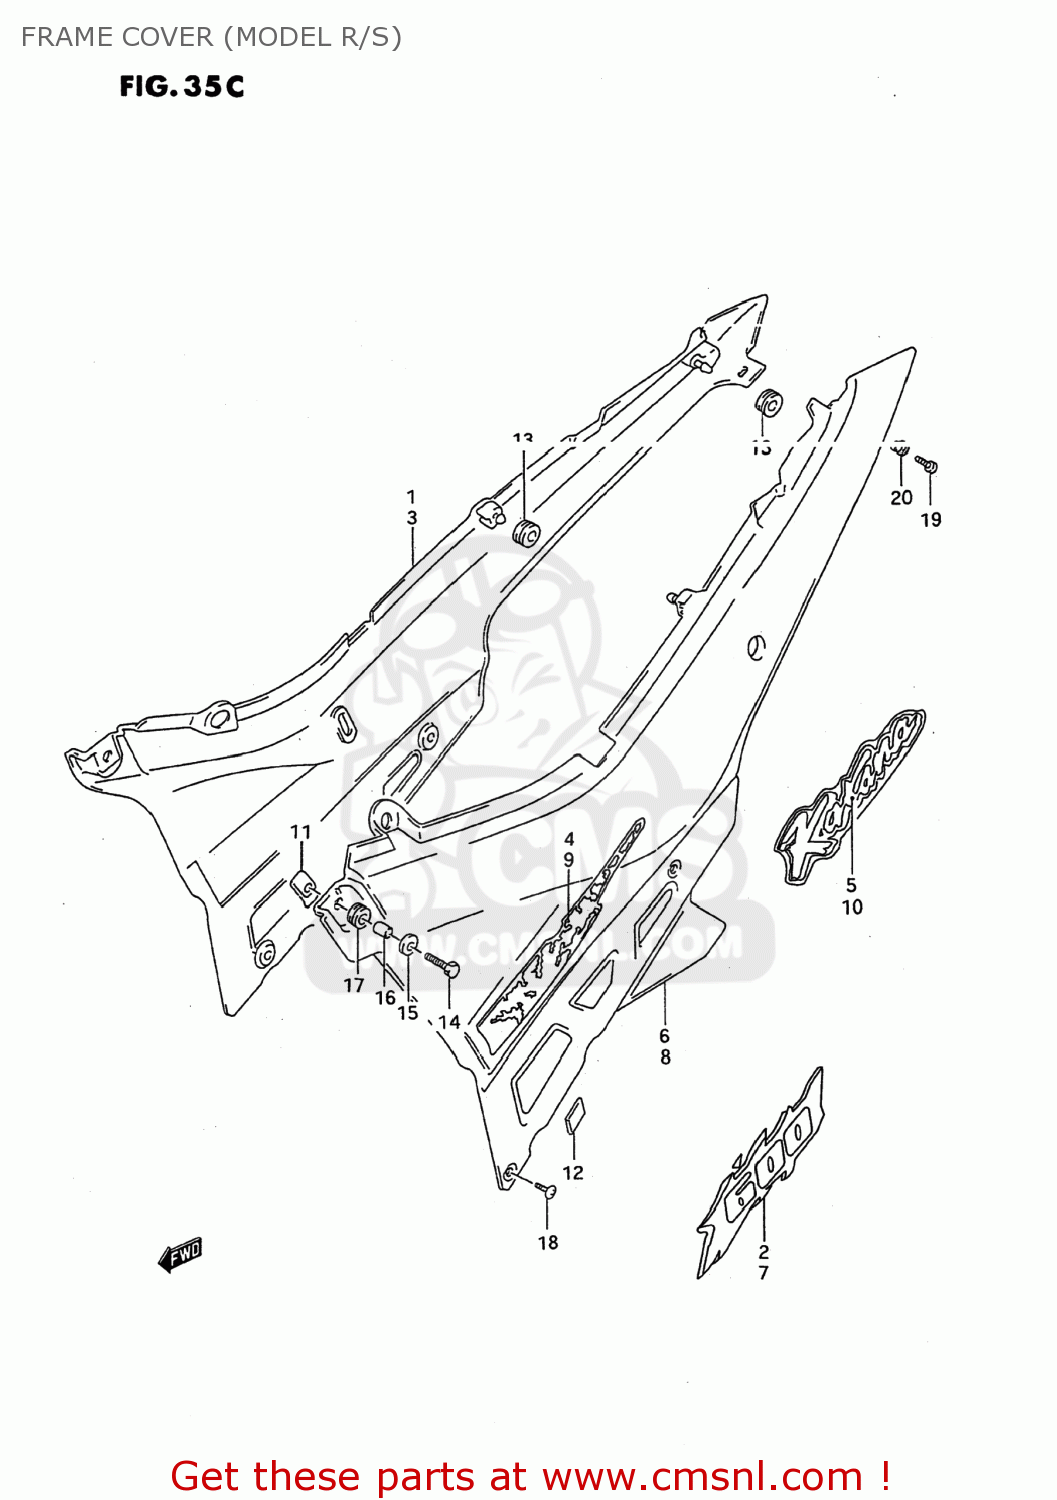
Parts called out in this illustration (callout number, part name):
1	COVER,FRAME,R
2	EMBLEM,FRAME COVER
3	COVER COMP,FRAME,RIGHT
4	TAPE,FRAME COVER,RIGHT
5	EMBLEM,FRAME COVER,RIGHT
6	COVER COMP,FRAME,LEFT
7	EMBLEM,FRAME COVER
8	COVER COMP,FRAME,LEFT
9	TAPE,FRAME COVER,L
10	EMBLEM, LH
11	PLATE,FRAME COVER
12	CUSHION,FRAME COVER
13	CUSHION
14	SCREW(6X20)
15	WASHER
16	SPACER (6.1X9X9)
17	CUSHION
18	SCREW(5X15.3)
19	SCREW 5X12
20	WASHER
